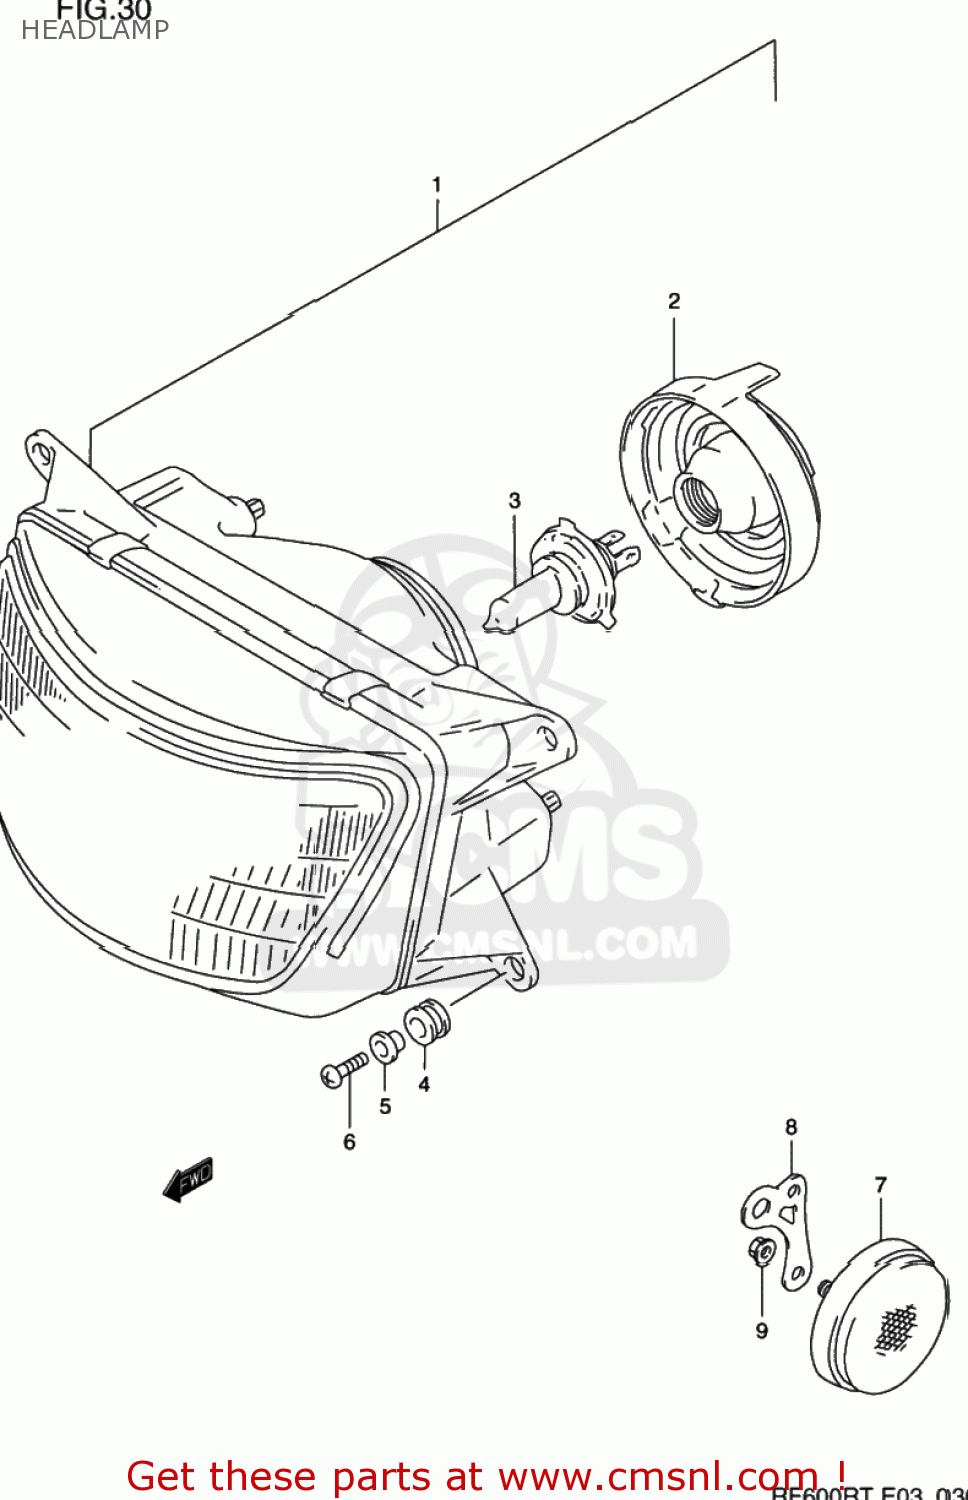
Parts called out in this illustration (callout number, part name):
1	HEADLAMP ASSY
2	COVER,SOCKET
3	BULB(12V60/55W,H4)
4	CUSHION
5	WASHER
6	SCREW
7	REFLECTOR,REFLEX FR
8	BRACKET,FR SIDE REFLECTOR
9	NUT
